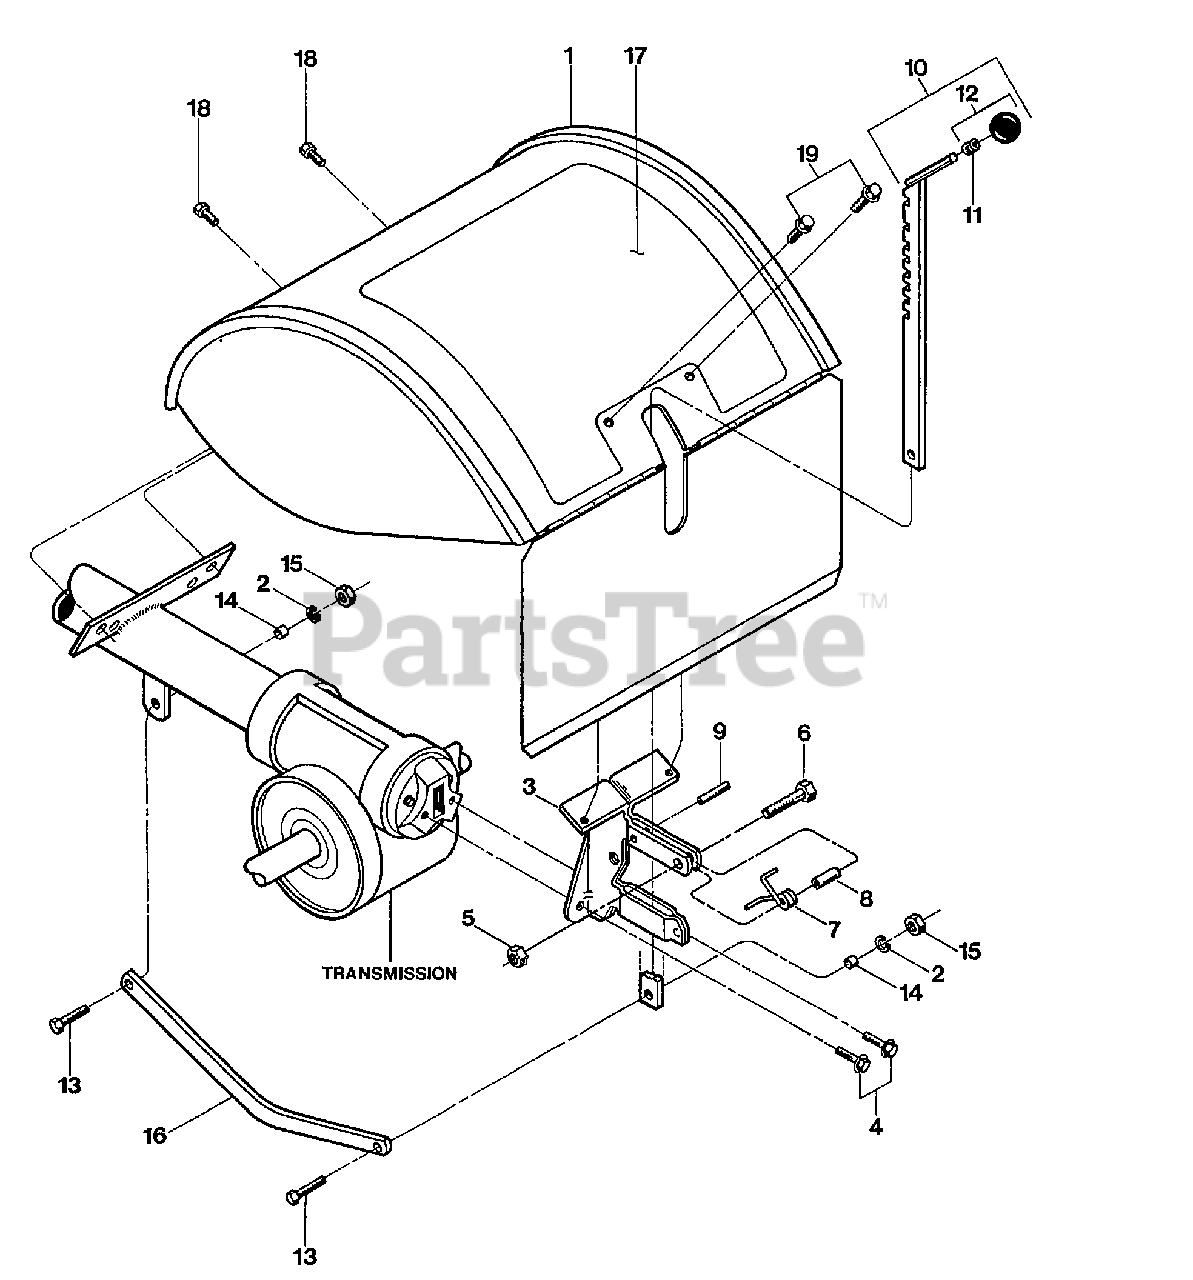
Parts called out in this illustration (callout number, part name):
1	HOOD W/DECAL ECONO OPC (INCL. #17)
2	WASHER-LK .375 @ DEPL
3	BRKT W/ROLL PIN (9308)(INCL. #9)
4	SCR-HFLK 5/16-18X.62 G5ZP
5	NUT-LK 1/4-20
6	SCR-HH 1/4-20X1.0
7	SPRING-TORSION
8	SPACER-.250X.343X.375
9	PIN-ROLL .25 X 1
10	DEPTH REGULATOR W/KNOB (INCL. #11 & 12)
11	RING-TOLERANCE .5325 ID
12	KNOB-CONTROL (INCL. #11)
13	SCR-HH 3/8-16X1.25
14	BUSHING-.5X.375X.3
15	NUT-HEX 3/8-16 ZP
16	DRAG BAR-BENT
17	DECAL-HOOD OPER INST
18	SCR-HWH 5/16-18 X .5 STH
19	SCR-HWH 1/4-20 X .5 STH
